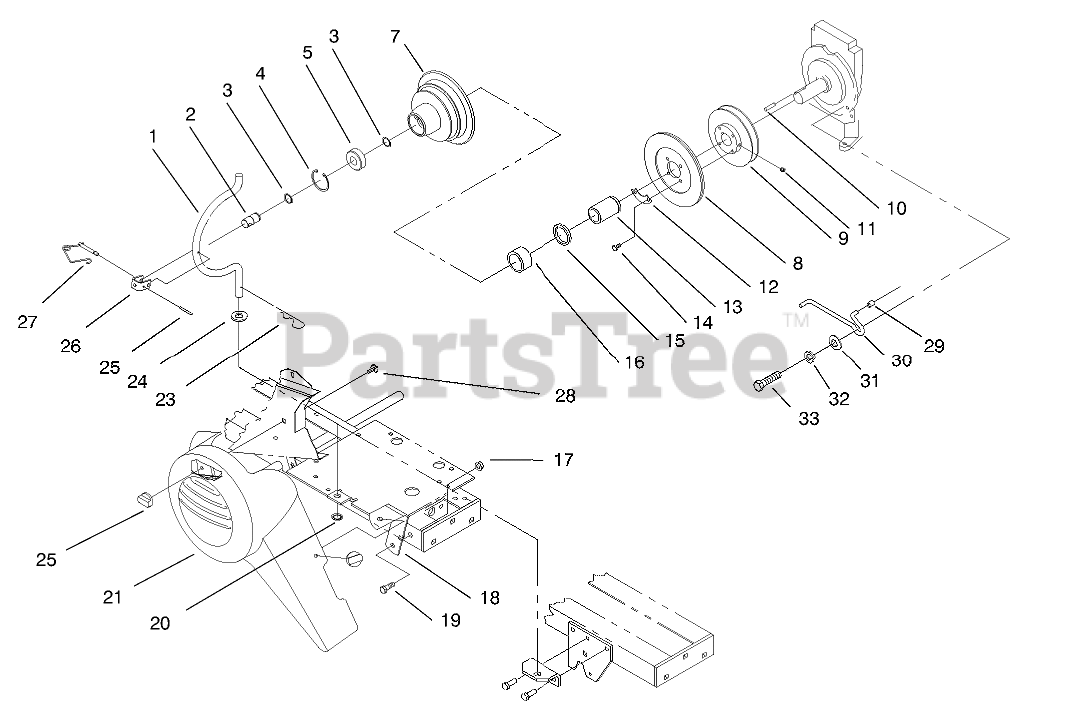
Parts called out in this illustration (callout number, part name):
1	ROD-HOUSING
2	SHAFT-PTO
3	Ring-Snap
4	RING-RETAINING
5	BEARING-BALL
7	Housing-Clutch
8	ASS'Y-CLUTCH PLATE
9	PULLEY
11	SCREW-SET, HSH
12	RETAINER
13	RACE-BEARING
14	SCREW-HEX HD CAP
15	SEAL-OIL
16	Seal
17	NUT-FLANGE
18	Bracket
19	SCREW-HH
20	RING-REINFORCED CIRC
21	GUARD - BELT
22	NUT - WING
23	PIN-COTTER, HAIR
24	WASHER-FLAT
26	CLEVIS
27	LOCKING PIN ASM
28	Retainer-Bolt
30	GUIDE BELT
31	WASHER-FLAT
32	WASHER-LOCK
33	SCREW-HH
